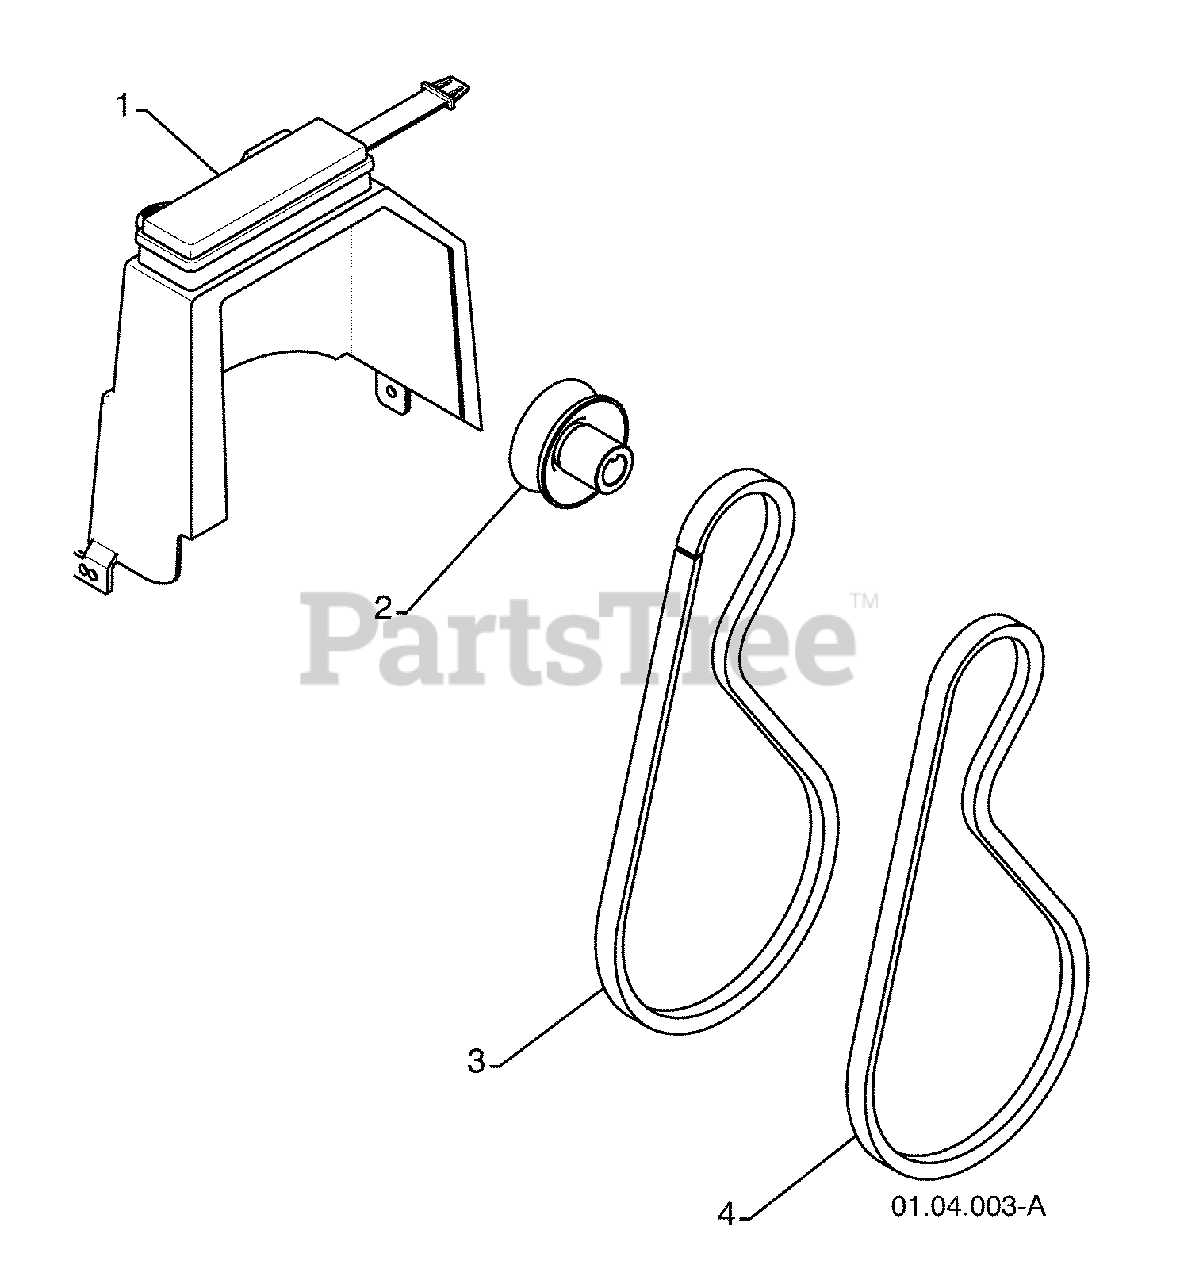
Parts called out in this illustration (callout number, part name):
1	COVER ASSEMBLY
2	PULLEY
3	TRACTION BELT
4	IMPELLER BELT
